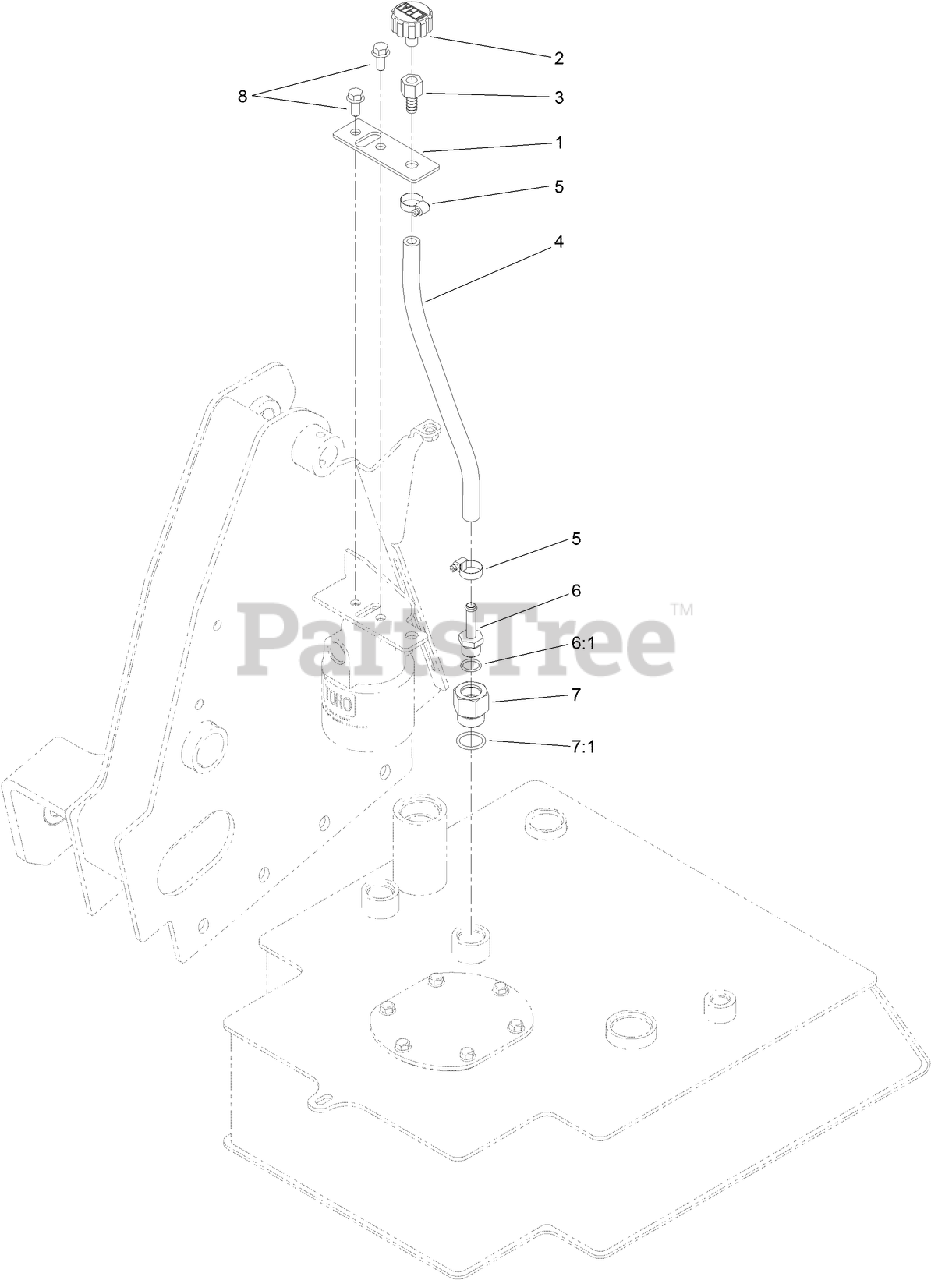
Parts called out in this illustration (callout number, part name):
1	BRACKET-FILTER
2	BREATHER
3	FITTING-FEMALE, BARBED
5	CLAMP-HOSE
6	FITTING-STRAIGHT
6:1	O-RING
7	FITTING-STRAIGHT
7:1	O-RING
8	SCREW-HHF
